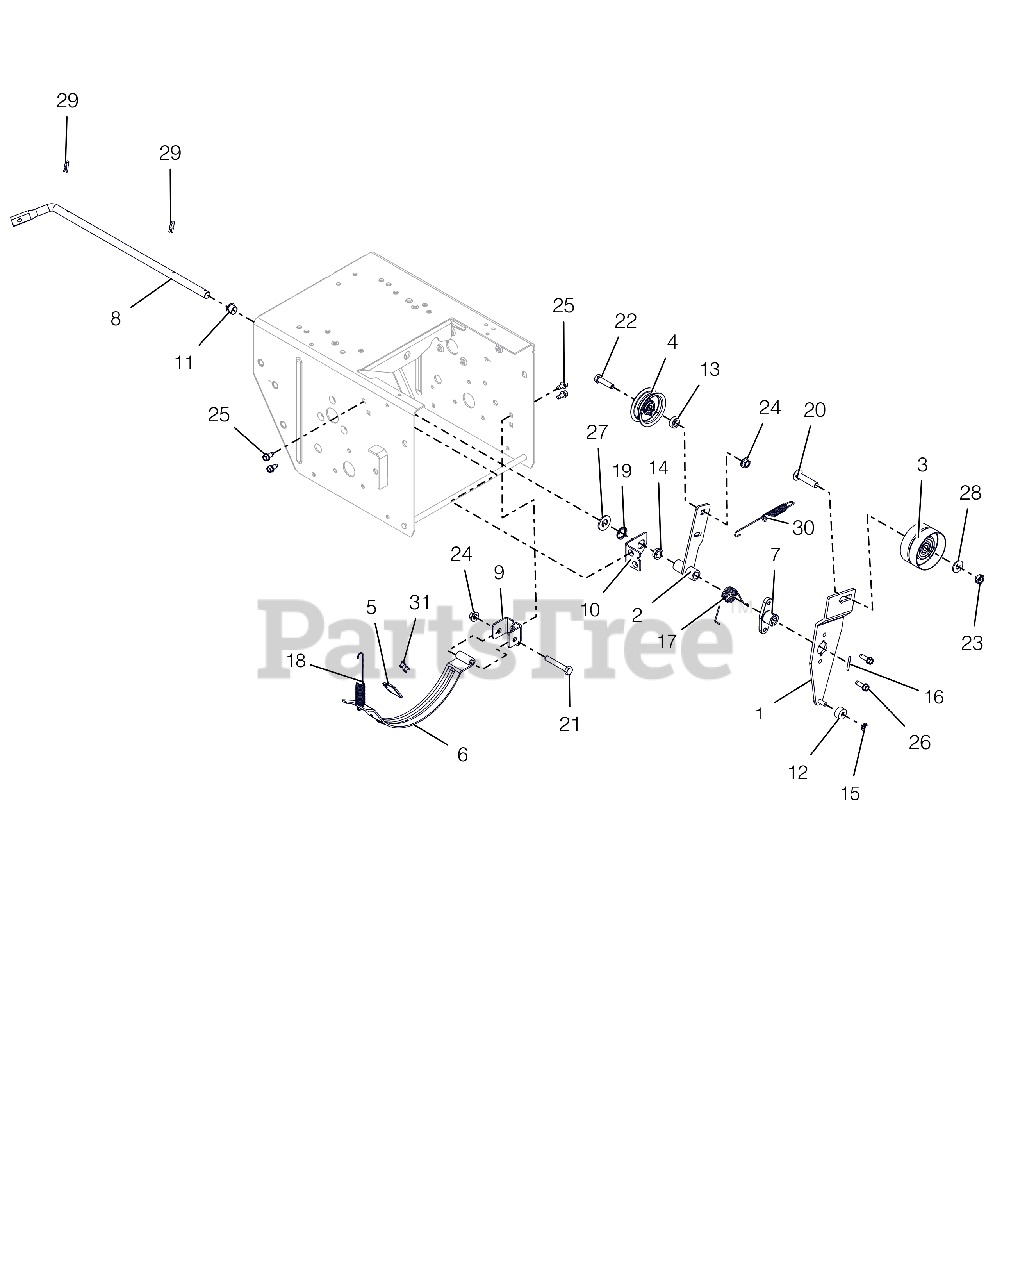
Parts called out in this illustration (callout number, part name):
1	ARM, IDLER-ATTACHMENT
2	ARM, IDLER-TRACTION
3	IDLER, FLAT-2.75 OD X .375 ID
4	IDLER, FLAT - 2.00"
5	PAD, BRAKE
6	ARM, BRAKE-ATTACHMENT
7	HUB, BRAKE ARM
8	ARM, ATTACHMENT
9	PIVOT, BRAKE
10	BRACKET, SUPPORT
11	BUSHING, POLYLINER-.50 SPLIT
12	BSHG,SLV .265 X .625 X .375
13	SPCR, BRG .315X.500X.358X.281
14	BSHG,FLANGE .500X.625X.270X.75
15	RG-RTNG-EXT .250X.010
16	PIN-ROLL .125X1.00
17	SG-TORS .067X.88
18	SG-TENS .056X.60X4.40
19	WAVE SPRING .600X.875X.25FH
20	@BLT-RHDSSQNK .38-16X1.75 G5YZ
21	@BLT-HEX .31-18X2.00 GR5 YWZC
22	@BLT-HEX .31-18X1.25 GR5 YWZC
23	@NUT-LK-CTR-JAM .375-16 YWZC
24	@NUT-LK-TOP-FLG .31-18 YWZC
25	SCR-TAP .25-20X.50 HWH TR YWZ
26	SCR-TAP-PM .25-20X.75 TR YWZ
27	@WSHR-FL-STL.531X1.06X.095YWZC
28	@WSHR-FL-STL.38X.875X.083 YWZC
29	CLIP, SPRING
30	SG-TENS .06X.482X5.35
31	RVT-POP .187 YZ
